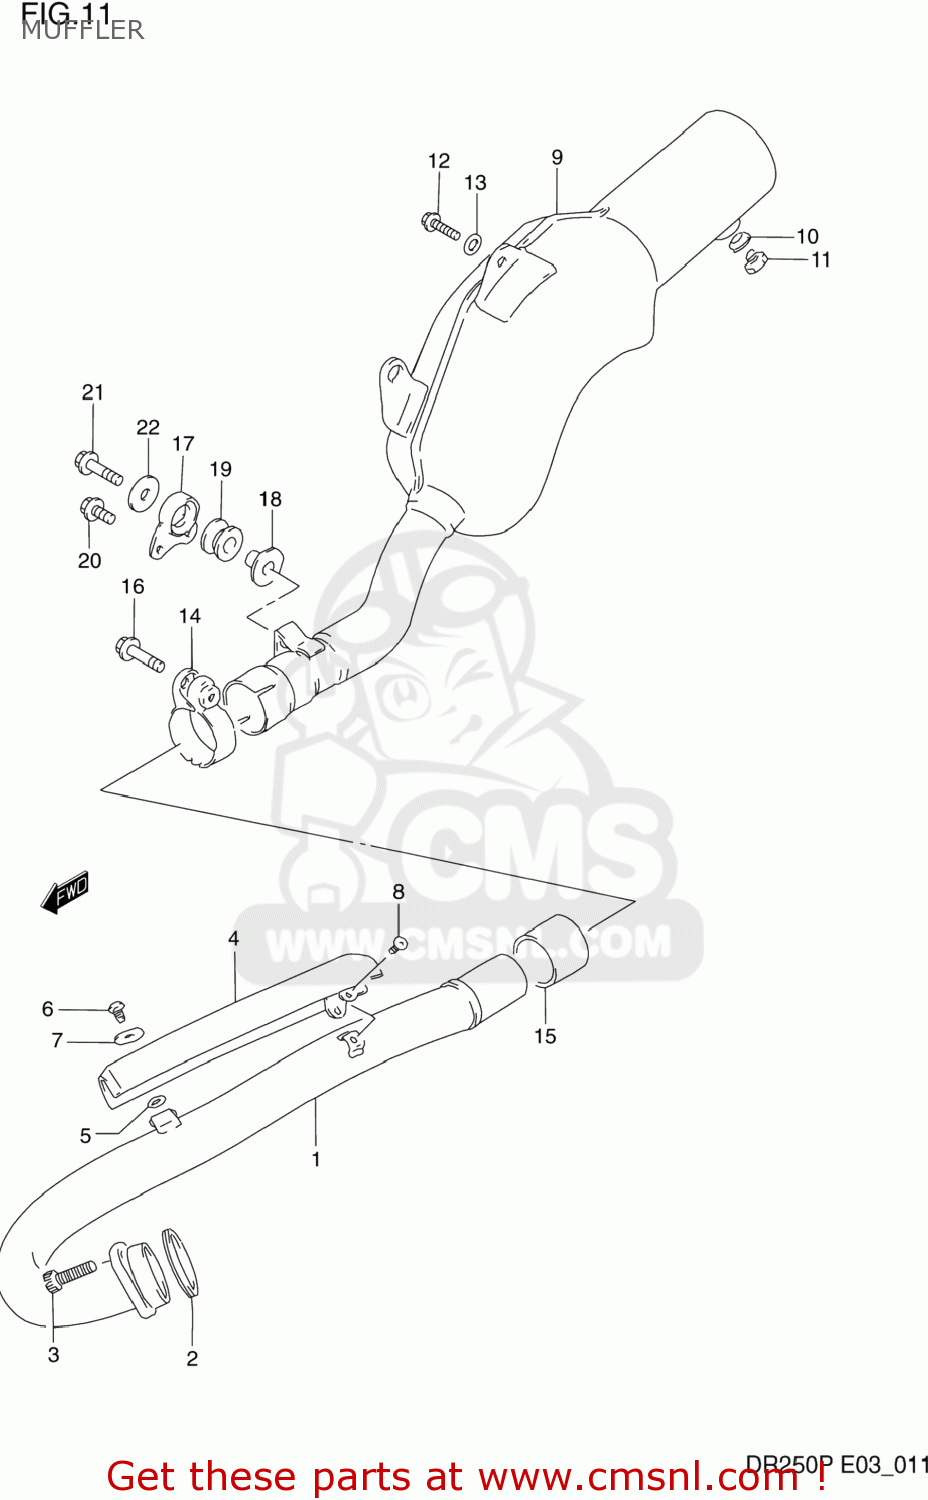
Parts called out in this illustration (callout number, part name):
1	PIPE,EXHAUST
2	GASKET,EXHAUST (NAS)
3	BOLT
4	COVER,EXHAUST PIPE
5	GASKET(5.8X13X1.4) (NAS)
6	SCREW
7	WASHER(6.5X18X1)
8	SCREW
9	BODY,MUFFLER
10	GASKET(12.1X16.2X3.7) (NAS)
11	PLUG(12X9)
12	BOLT(8X20)
13	WASHER (8.5X19X2.3)
14	CLAMP,PREMUFFLER CONNECTOR,L
15	CONNECTOR,MUFFLER JOINT
16	BOLT
17	DAMPER,MUFFLER SUPPORT
18	SPACER(8.6X12X17.5)
19	CUSHION
20	BOLT
21	BOLT 8X35
22	WASHER (8.5X20X1.6)
